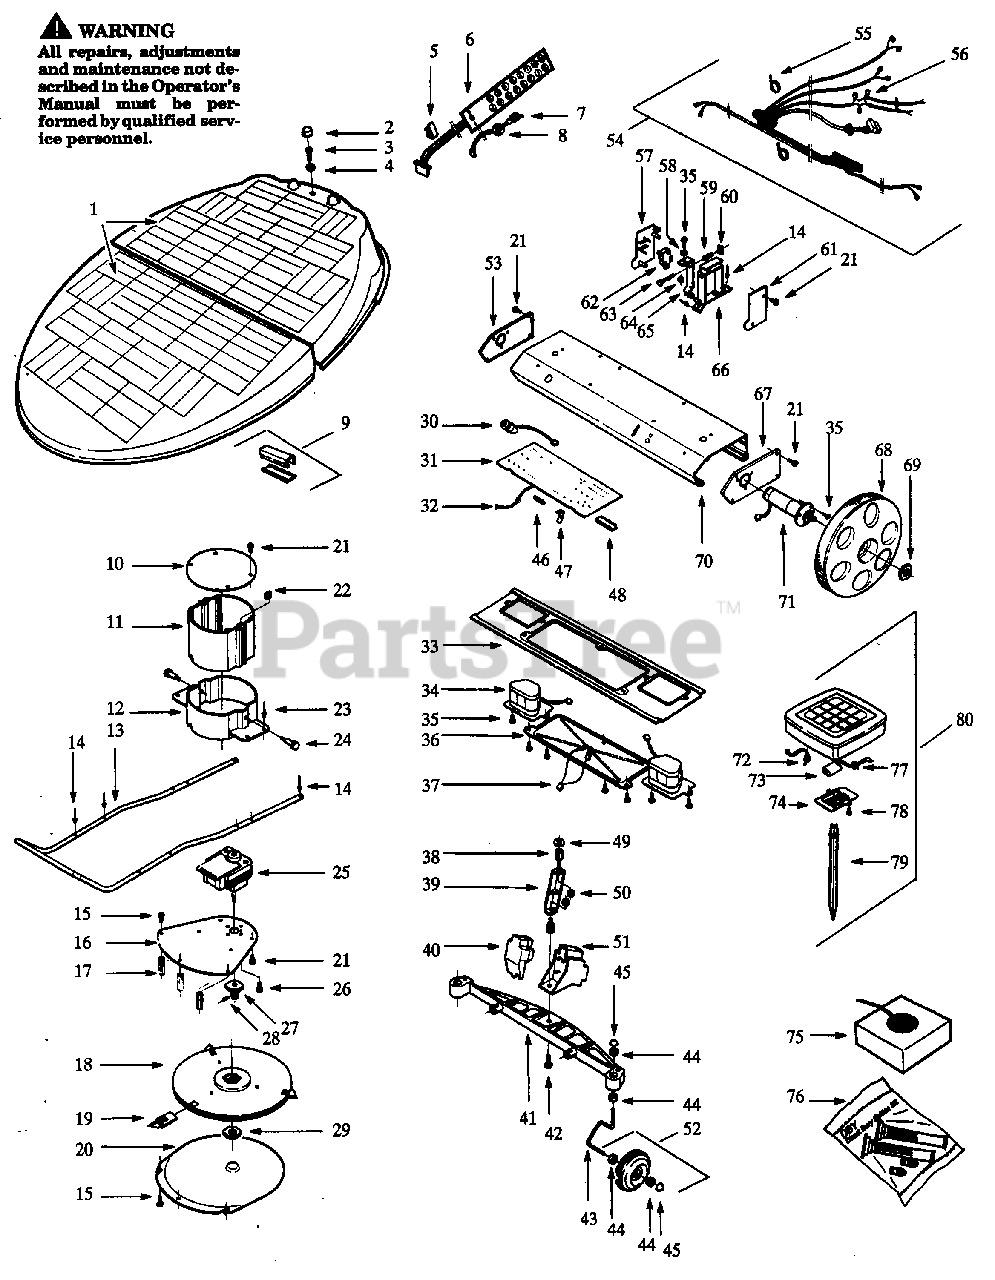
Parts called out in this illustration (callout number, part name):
1	Solar Cell Kit
2	Cover-Shock Screw
3	Screw-Shock Top
4	Washer-Top Shock
6	Keyboard
7	On/Off Switch
8	Switch Nut
9	Wire Connection Protector
10	Top Motor Housing
11	Blade Motor Housing
12	Blade Motor Mount
14	Pop Rivet
16	Bottom Motor Plate
17	Spacer Motor Plate
18	Cutting Disc Assembly
19	Blade Kit (3 blades)
20	Skid Plate
22	Square Nut
23	Pop Rivet
24	Adjusting Screw
25	Cutting Motor
26	Motor Mount Screw
28	Set Screw
31	Circuit Board
32	Ground Wire
33	Cover-Electric Housing
34	Battery Pack
36	Cover-PC Board
37	Moisture Sensor Wire
38	Vibration Mount
40	Sensor Cover
41	Front Axle
42	Shock Screw
43	Wheel Spindle
45	Cover-Bearing
47	Spring Clip
48	Microcopressor
52	Front Wheel Assembly
53	Left Gable
54	Wire Harness
55	Tie Strap
56	Wire Connector
57	Right Cover
59	Spring-Microswitch
60	Adjusting Nut
61	Cover Left
62	Microswitch
65	Bracket Microswitch
66	Bracket Microswitch
67	Right Gable
68	Drive Wheel
70	Electric Housing
71	Drive Motor
72	Generator Switch
73	Generator Battery
74	Generator Battery Cover
75	Boundary Wire
76	Splice Kit
79	Generator Stake
80	Generator Assembly
